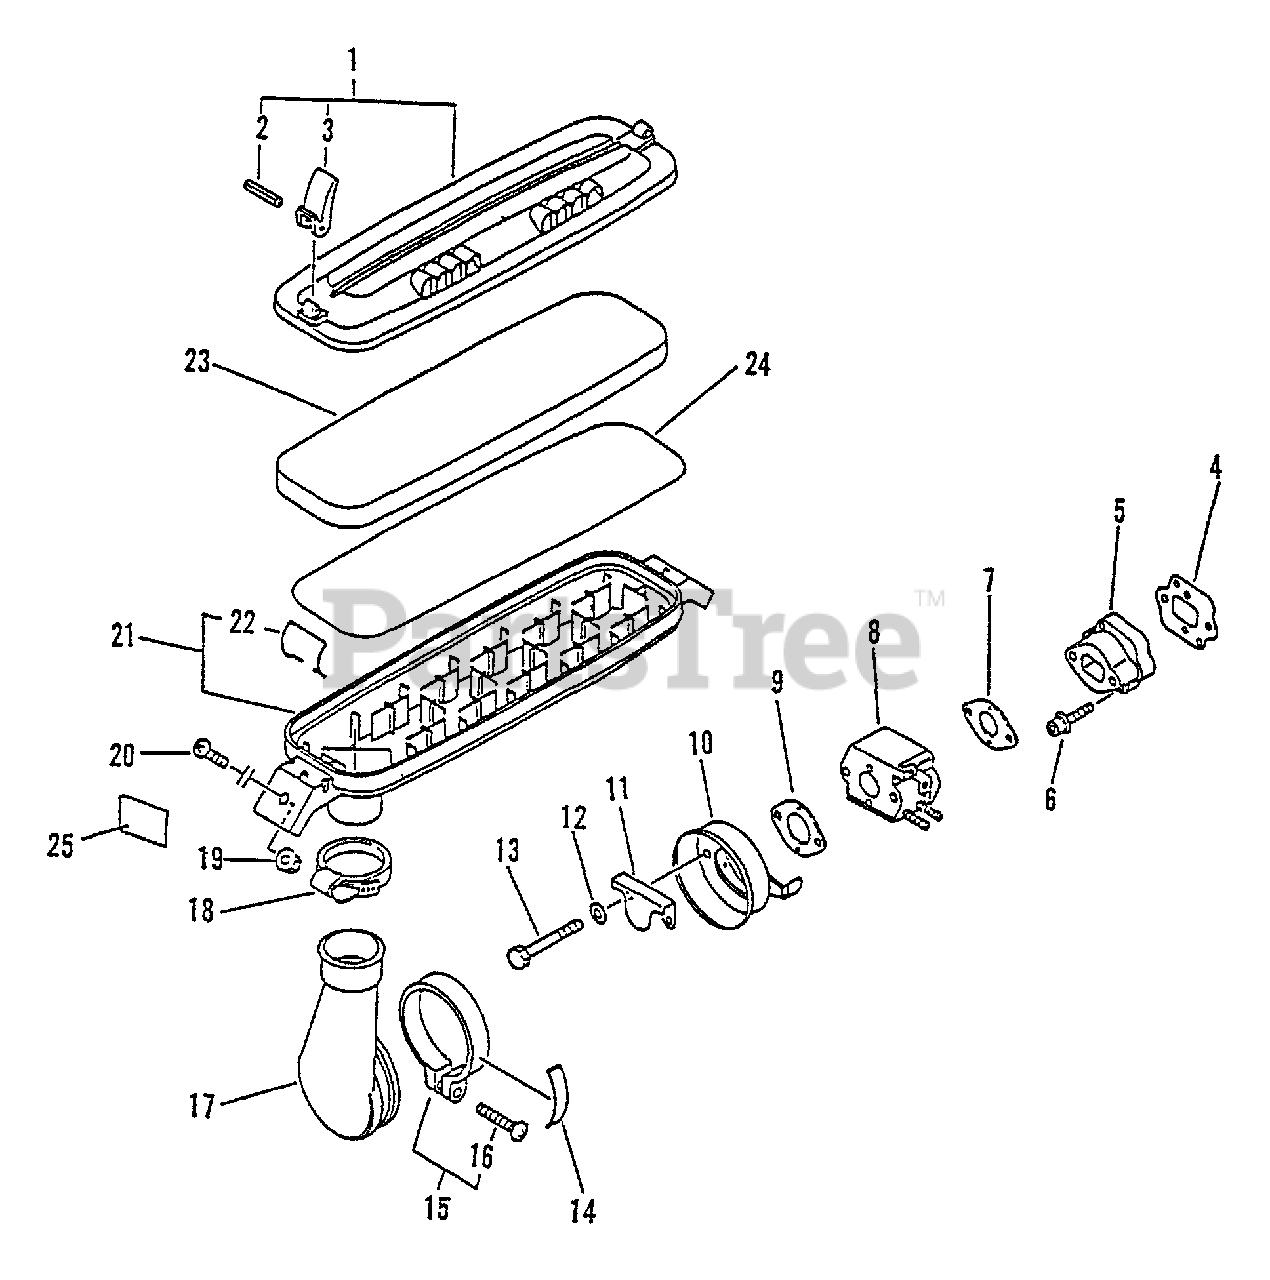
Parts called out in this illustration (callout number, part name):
1	COVER, AIR FILTER
2	PIN, SPRING 3×25
3	KNOB
4	GASKET, INTAKE
5	INSULATOR, INTAKE
6	BOLT 5×25
7	GASKET, INTAKE
8	CARBURETOR - C1M-K24A
9	GASKET, INTAKE
10	BRACKET, AIR FILTER
11	PLATE, PREVENT
12	WASHER 5.5×12×0.8
13	SCREW 5×50
14	LABEL, CHOKE
15	CLAMP KIT
16	SCREW 5×25
17	ADAPTOR, INTAKE
18	BAND
19	NUT, FLANGE M5
20	SCREW - 5×14
21	AIR FILTER CASE ASSY
23	FILTER, AIR
24	FILTER, AIR
25	LABEL, CLEANER
